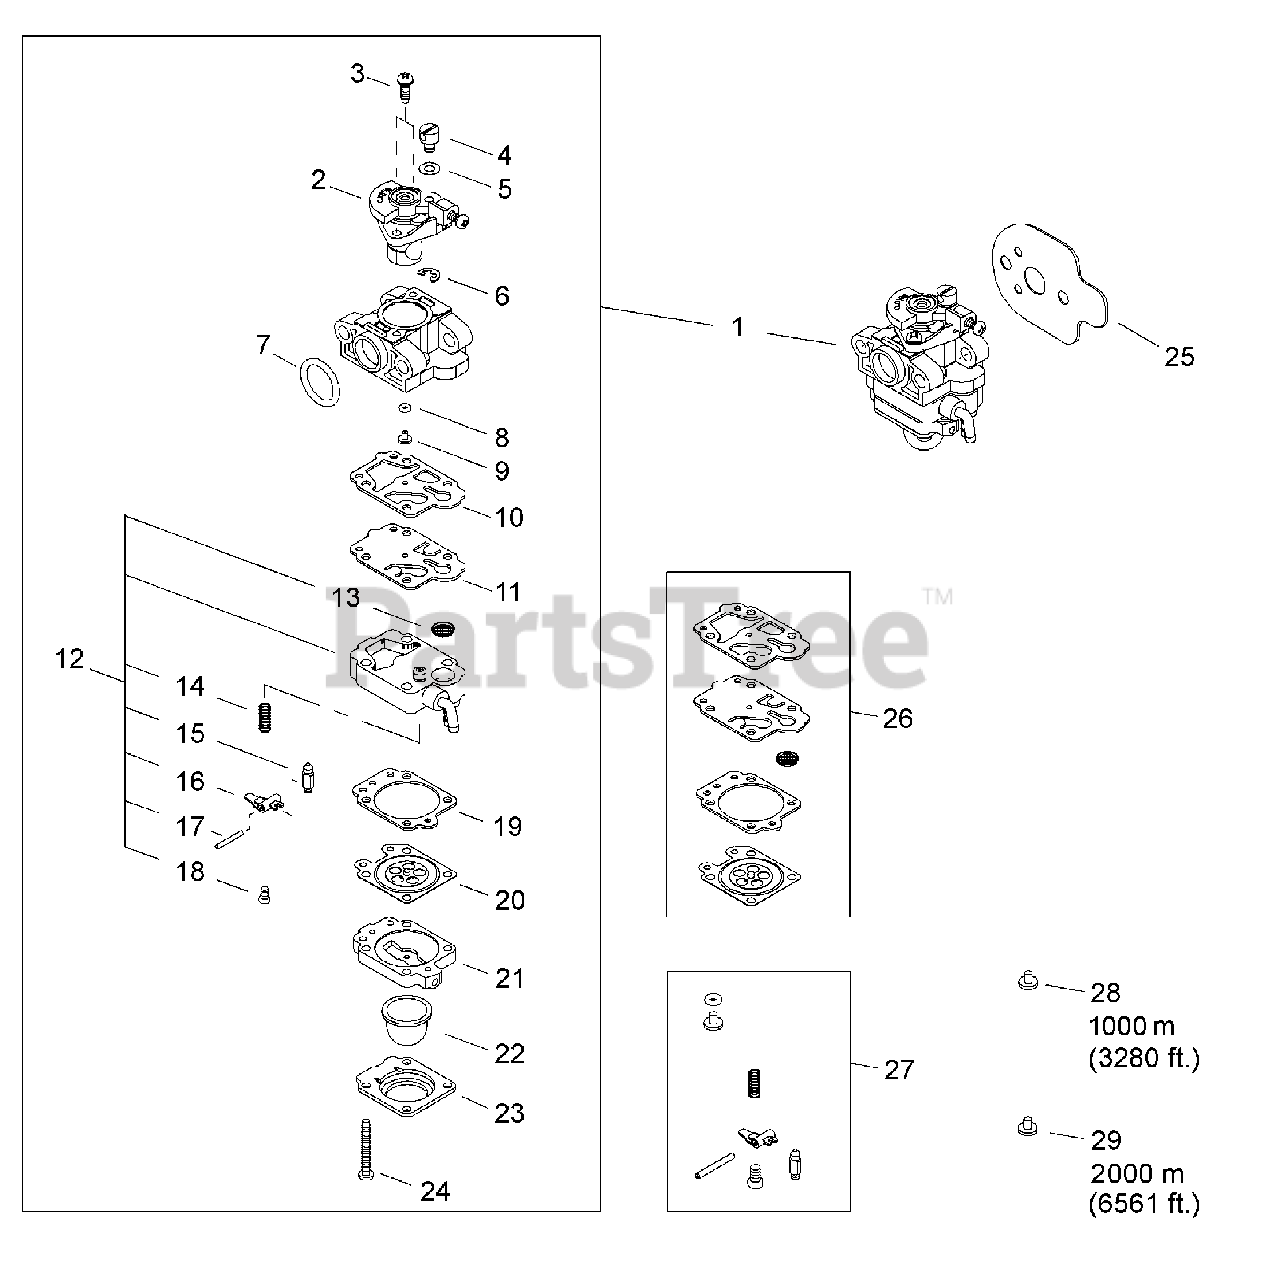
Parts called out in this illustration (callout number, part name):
1	CARBURETOR
2	THROTTLE VALVE ASSY
3	SCREW
4	SWIVEL
5	WASHER
6	RING, RETAINING
7	O-RING - 15
8	O-RING
9	JET, MAIN
10	GASKET, PUMP
11	DIAPHRAGM, PUMP
12	PUMP BODY ASSY
13	STRAINER
14	SPRING, METERING LEVER
15	VALVE, INLET NEEDLE
16	LEVER, METERING
17	PIN, METERING LEVER
18	SCREW, METERING LEVER PIN
19	GASKET, METERING
20	DIAPHRAGM, METERING
21	BASE, PURGE
22	BULB, PURGE
23	RETAINER, PURGE BULB
24	SCREW, PUMP COVER
25	GASKET, INTAKE
26	DIAPHRAGM/GASKET KIT
27	INLET NEEDLE VALVE KIT
28	JET, MAIN - 1000M #40
29	MAIN JET - 2000M #39
